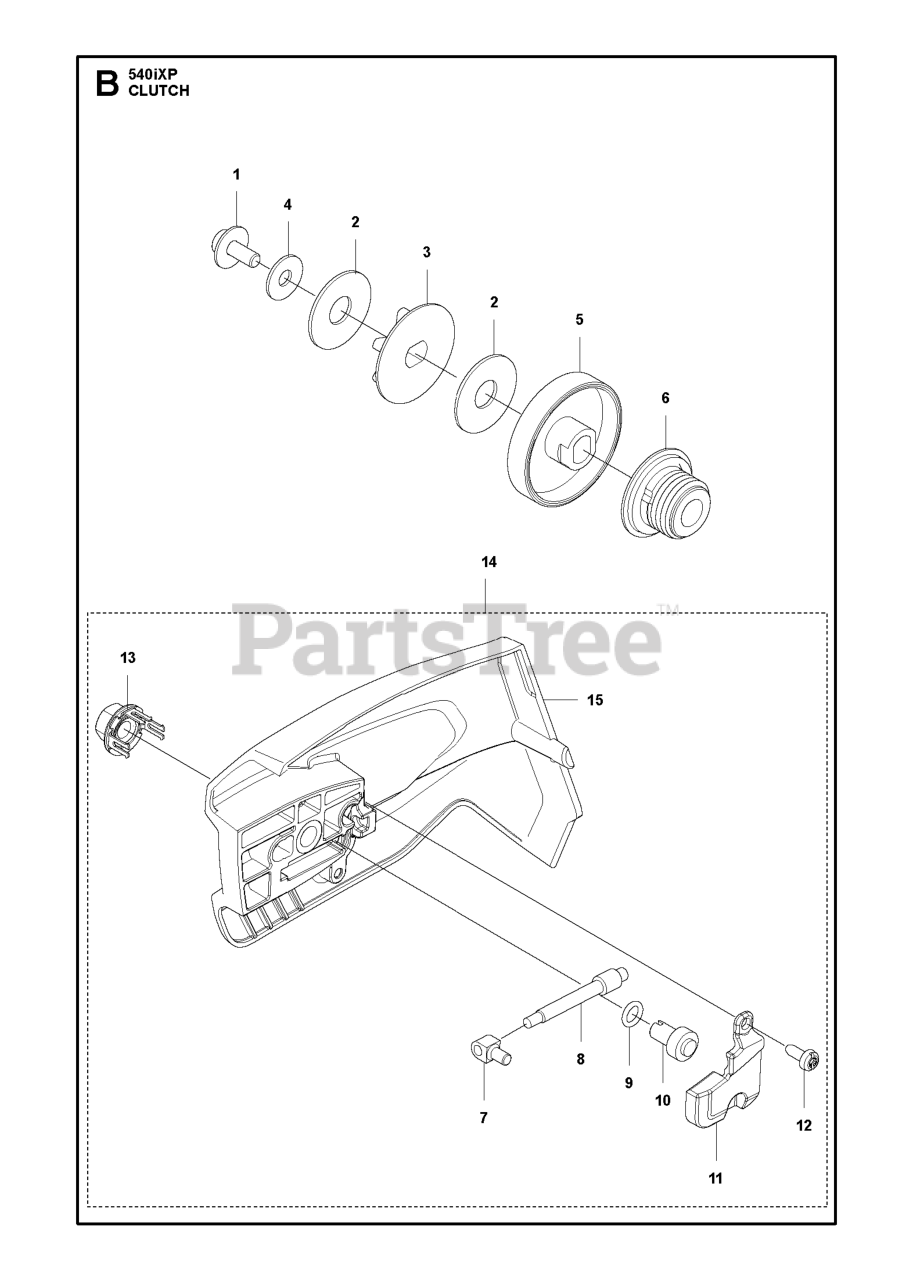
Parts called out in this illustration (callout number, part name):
1	SCREW
3	Sprockets
3	SPUR SPROCKET 3/8" - 6T
4	WASHER 5.3X15
6	Pumps
7	PIN BAR ADJUSTING
10	WORM WHEEL LEFT HAND TEETH
11	COVER LID
13	NUT RETAINER ASSY
14	CLUTCH COVER
15	CLUTCH COVER 540I XP
